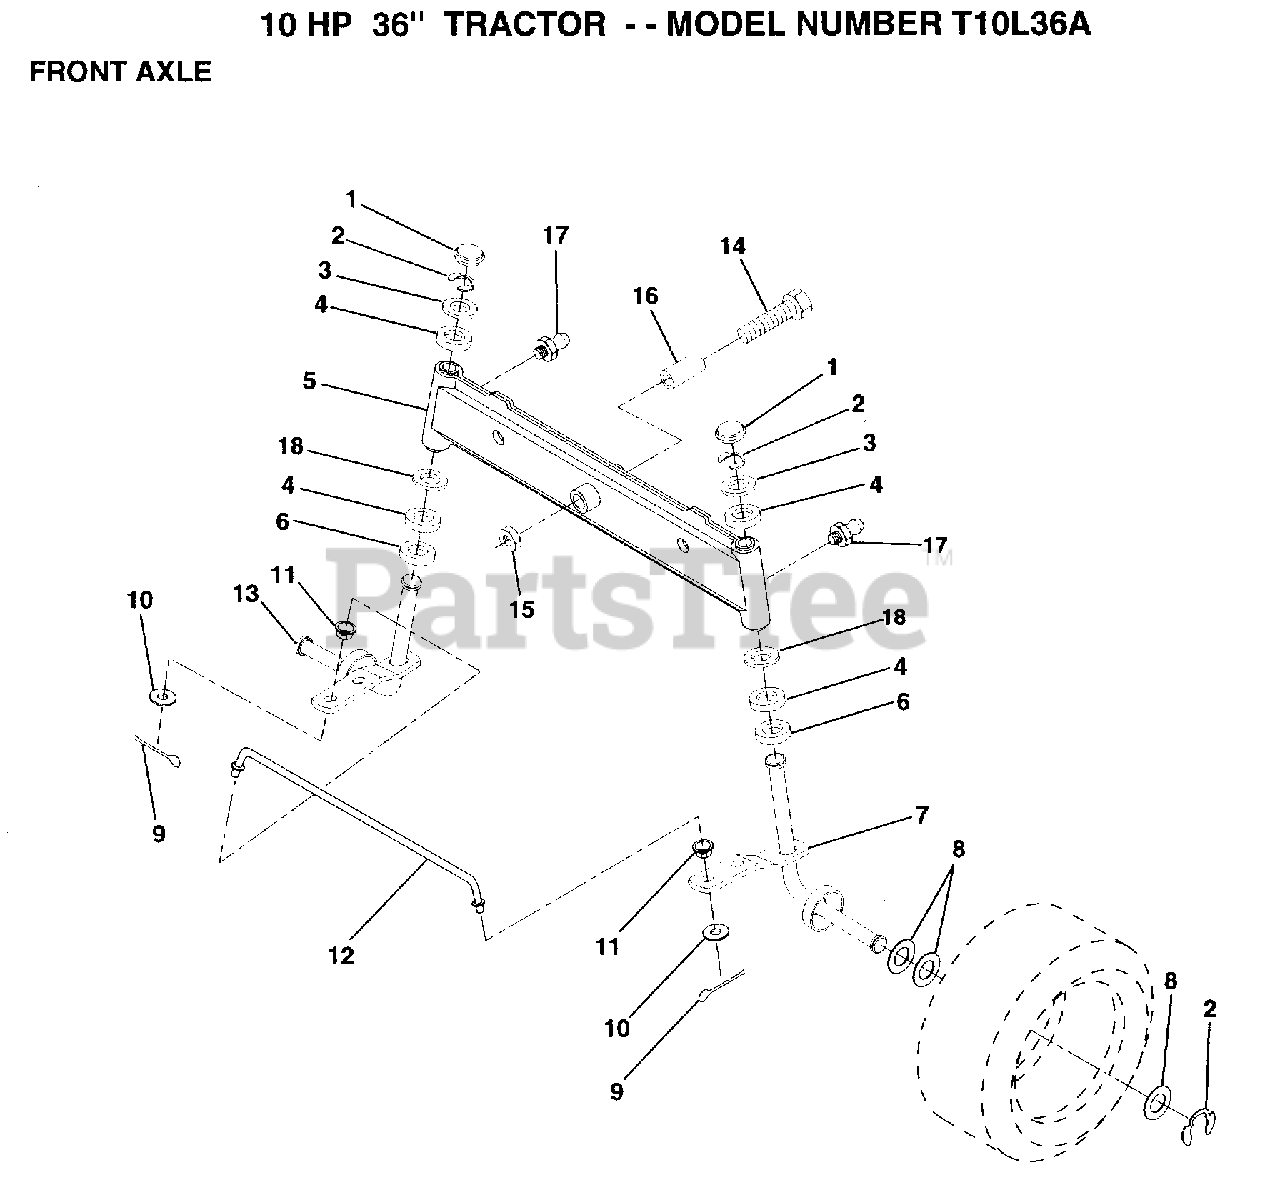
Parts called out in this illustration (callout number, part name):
1	CAP
2	RING
3	WASHER
4	COL. SRTG. BEAR.
5	AXLE ASM FRONT
6	WASHER .T
7	SPINDLE ASM RH
8	WASHER
9	COTTER PIN
10	WASHER
11	BUSHING.DRAGLINK
12	TIE ROD
13	SPINDLE ASM LH
14	BOLT HEX 5/8-11
15	"NUT-LOC,FLANGE LT"
16	BEARING
17	ZERK M
18	WASHER
